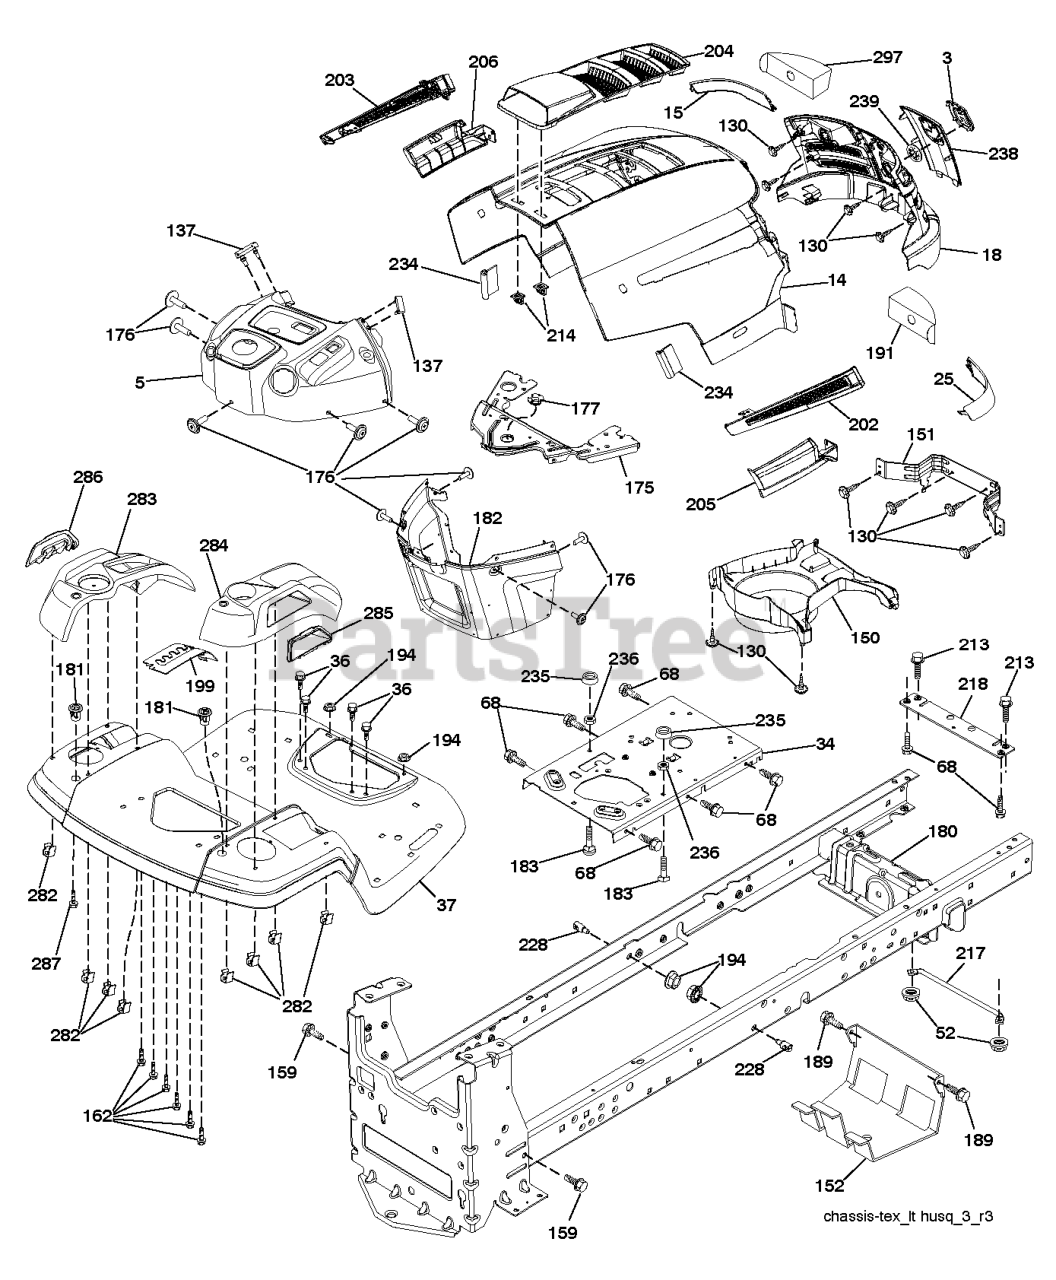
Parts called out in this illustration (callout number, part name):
3	RP LOGO
5	DASH
14	HOOD.HUSQVARNA.LT.ORANGE
15	LENS.HUSQVARNA LT.LH
18	GRILLE.SVC.HUSQVARNA.LT.GREY
25	LENS.HUSQVARNA LT.RH
34	PLATE.ENGINE.WELDED.CHASSIS
36	SCREW 5/16"
37	RP FENDER.TLT.FS.W/CPH.422
52	LOCKNUT
68	Screw 5/16-18 x 1/2 Hex, Self Tapping 5/16-18 x 1/2
130	SCREW.#10 X 0.750.BOS
137	BUMPER DASH
151	BRACKET PIVOT
152	SHIELD.BROWNING.W/TEX
159	SCREW, 3/8-16X3/4
162	SCREW.HI-LO.CONSOLE
175	CROSSMEMBER
176	SCREW.#10-24X5/8.RN.QU
177	BUSHING STEERING
180	CHASSIS
181	BUSHING.MNT.FEND.CRGO.
182	DASH.LOWER.PREDATOR LT
183	BOLT.5/16-18X1-1/4 FULL THD
189	SCREW
191	INSERT.REFLECTIVE.RH.
194	NUT LOCK HEX FLANGE 5/16-18
199	PLATE.DECK.LIFT.HUSQ.LT
202	VENT SIDE HOOD LH
203	VENT SIDE HOOD RH
204	VENT TOP HOOD
205	SKIRT SIDE RH
206	SKIRT SIDE LH
213	BOLT
214	CLIP.RETAINER.TINNER.
217	ROD.PIVOT.HOOD
218	X-PIECE.HOOD.STOP.NON/
228	STUD.FASTNER.W/ANTI-ROTATE
234	BUMPER.HOOD.TEX.HUSQVARNA
235	SPACER FENDER
236	NUT.CENTERLOCK.5/16-
238	TRIM
282	CLIP.RETAINER.CONSOLE.LT.HUSQ
283	CONSOLE.DECK.LIFT.HUSQ.N/FR.GR
284	CONSOLE.SHFT.HYD,HUSQL
285	CONSOLE INSERT RH
286	CONSOLE.INSRT.LH.HUSQ.LT.BLACK
287	SCREW 1/4X20
297	INSERT REFLECTIVE
